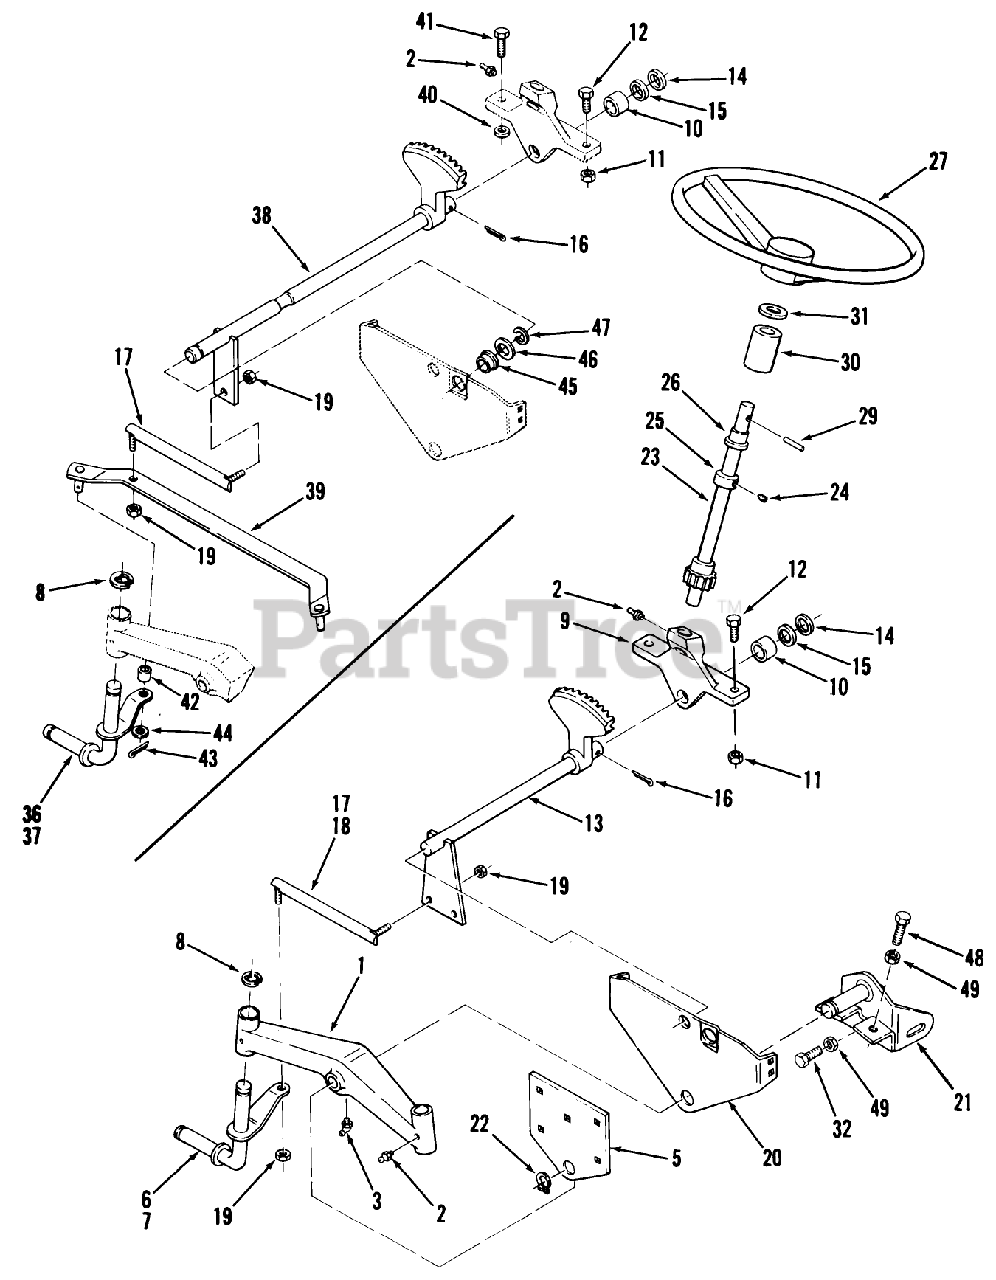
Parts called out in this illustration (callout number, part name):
3	FITTING-GREASE
10	BEARING-BRONZE
14	WASHER-SHIM
15	WASHER
26	BEARING
31	WASHER-BOWED
40	WASHER-FLAT
44	WASHER-FLAT
45	BUSHING
46	WASHER SPECIAL
